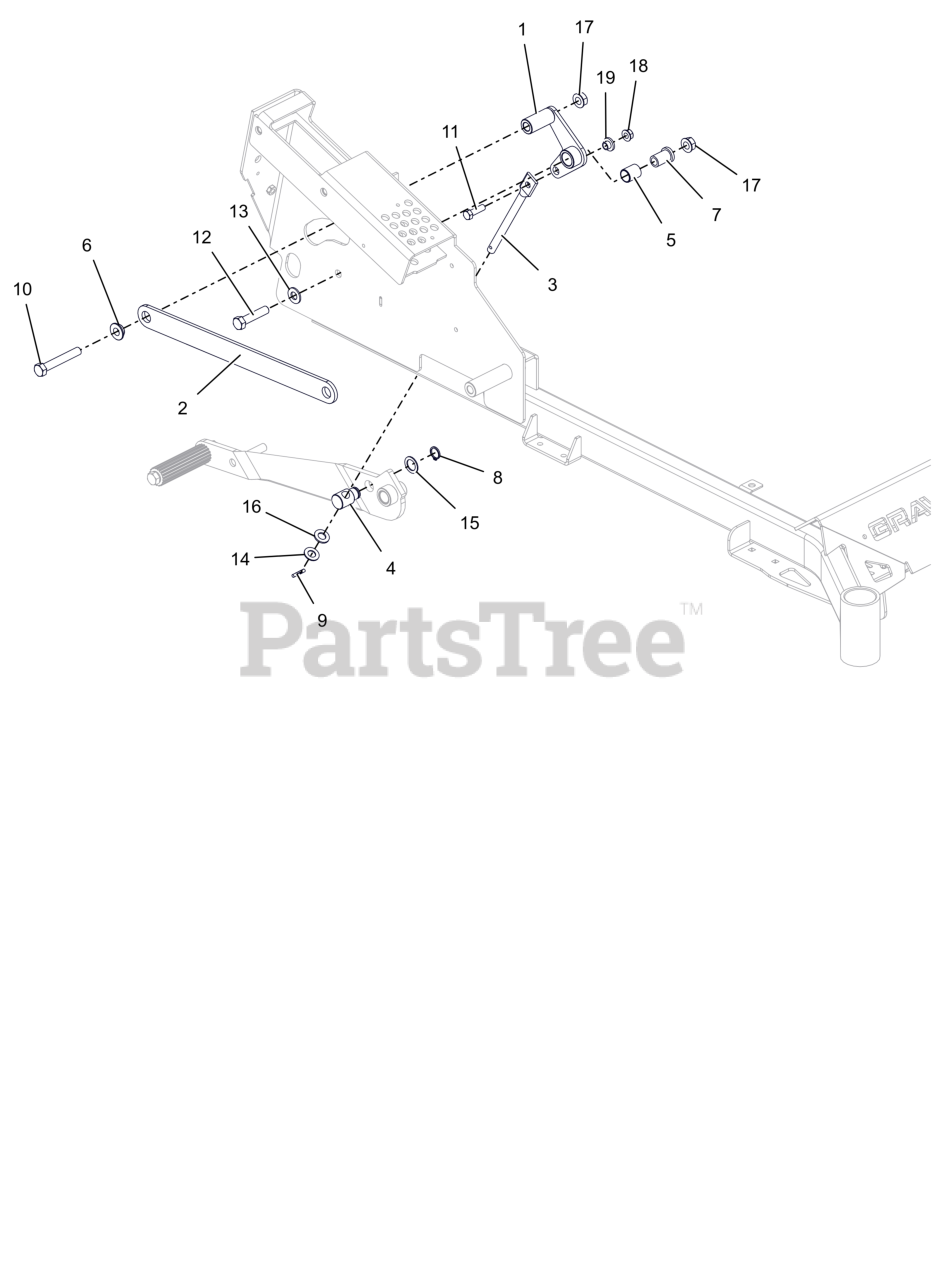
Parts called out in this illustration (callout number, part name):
1	WLDMT, PIVOT BRKT
2	LINK,36" DECK LIFT FOOT ASSIST
3	LINK, HOC FOOT
4	TRUNNION,DECK LIFT FOOT ASSIST
5	BRG, .750 X .875 X 1.000
6	BSHG, FLG .515X.750X.360X1.12
7	BSHG-FLG .515X.746X1.290X1.000
8	RG-RTNG-EXT .689X.078
9	PIN-GRV .188X1.00 TP E
10	BLT,HEX .50-13X3.25 G5 ZCC
11	BLT, HEX .38-16X1.25 G5 ZCC
12	BLT, HEX .50-13X2.25 G5 ZCC
13	WSHR,FLT .531X1.062X.095 ZCC
14	WSHR, FLT .531X1.00X.063 ZCC
15	WSHR, FLT .754X1.125X.062 ZCC
16	WSHR, RUBBER .332X1.000X.094
17	NUT-LK-CTR-FLG .500-13 GG ZCC
18	NUT-LK-CTR-FLG .375-16 GF ZCC
19	BSHG-FLG .385X.500X.875X.406
